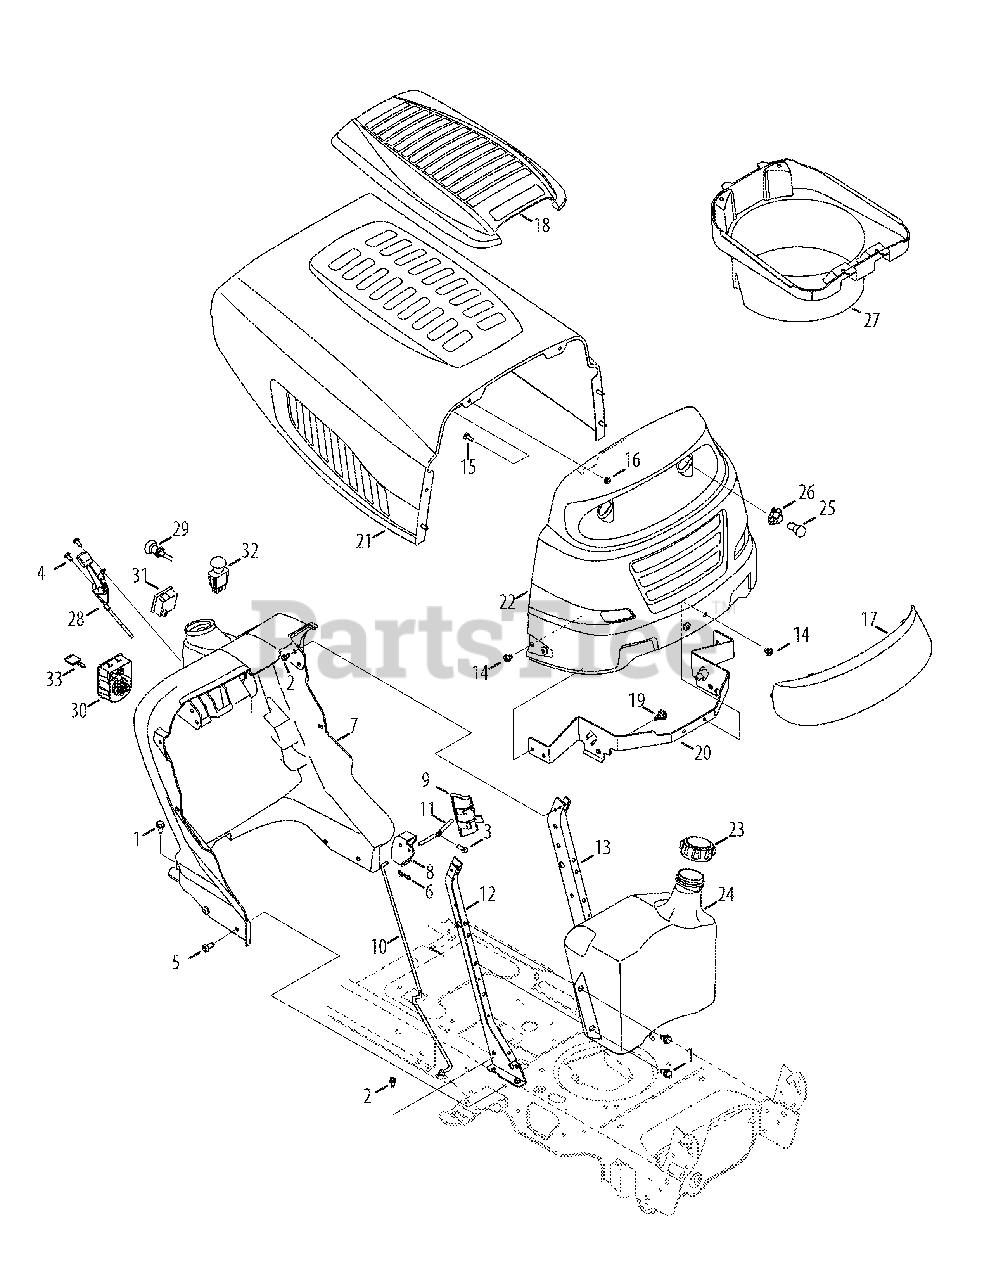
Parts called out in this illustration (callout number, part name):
1	Taptite Screw ,5/16-18:.750
2	Taptite Screw ,1/4-20:0.500
3	Hi-Lo Screw, 1/4-15:0.750
4	Screw, 1/4-14:0.625
5	Taptite Screw ,5/16-18:0.750
6	Bow Tie Cotter Pin
7	Dash Panel
8	Dash Lever
9	Cruise Cover
10	Control Rod
11	Lever
12	RH Support Plate
13	LH Support Plate
14	Taptite Screw ,5/16-18:0.375
15	Hex Screw, 1/4-20:.620
16	Flangelock Nut, 1/4-20
17	Grill Lens
18	Hood Scoop
19	Shoulder Screw, .43X.29:5/16-18
20	Hood Pivot Bracket
22	Grill
23	Fuel Cap
24	Fuel Tank
26	Lamp Socket
28	Throttle Cable
29	Choke Cable
30	Key Switch Module
31	Hour Meter
32	Electric PTO Switch
